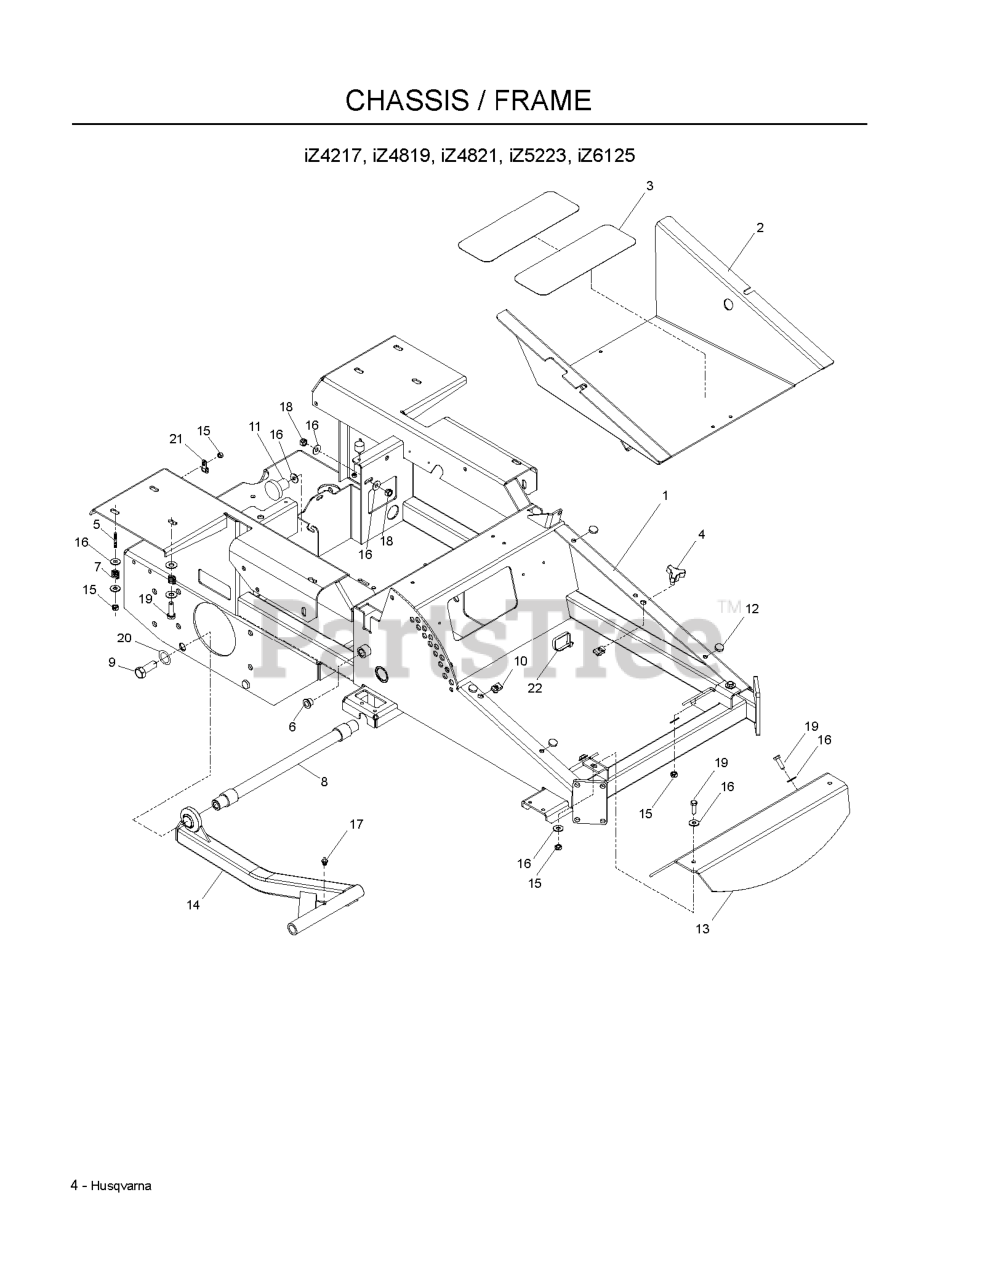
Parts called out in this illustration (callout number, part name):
1	IZ FRAME W/DECALS
2	IZ FOOTPLATE W/DECAL
3	ANTI-SKID PAD
4	KNOB W/STUD
5	STUD, 5/16C
8	STRUT MOUNT WELDMENT
9	HCS 5/8C X 2 GR.5
10	U-CLIP 5/16-18 NUT RETAINER
12	GROMMET, BUMPER
13	FOOTREST ORANGE
14	STRUT, LT
14	STRUT, RT
15	NUT 5/16 NYLOC
16	WASHER 5/16 FLAT
17	ZERK
18	NUT 5/16C CENTERLOCK
19	HCS 5/16C X 1
20	LOCKWASHER 5/8
21	DOUBLE TUBE CLAMP
22	TIE, PLASTIC
